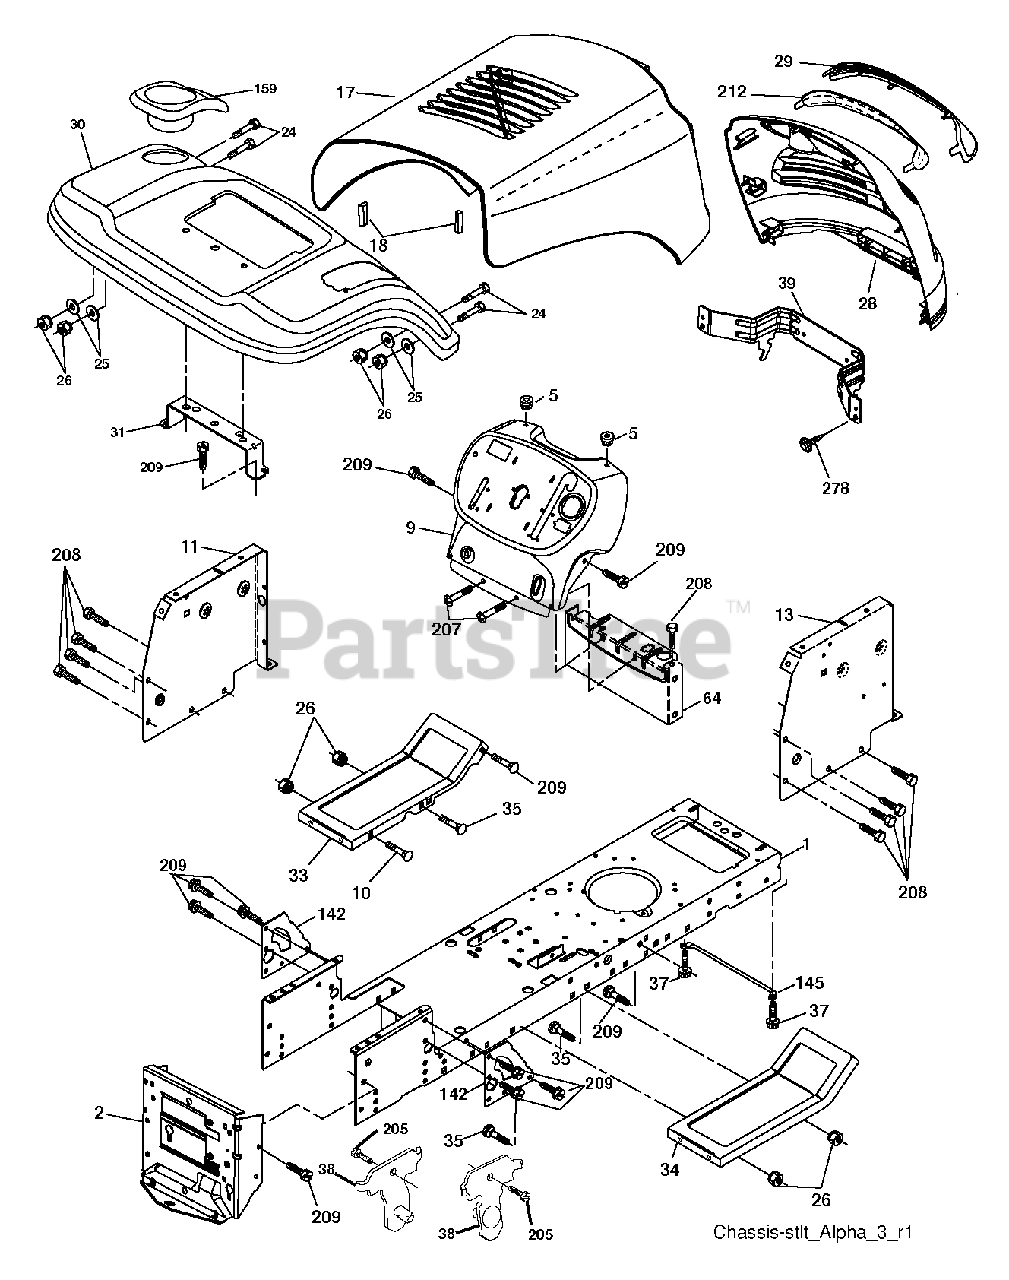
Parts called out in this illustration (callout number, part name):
1	CHASSIS STAMPING
2	DRAWBAR, 12GA
5	BUMPER.RUBBER.HOOD
11	PANEL.DASH.LH.LTX
13	PANEL
17	HOOD.BLACK.ALPHA
18	BUMPER.HOOD.LARGE.1.75"
25	WASHER
26	NUT
28	GRILLE.ASM.ALPHA
29	LENS.ALPHA.BAR.LT
30	FENDER.LTST.W/SHFT.CUP.BLACK
31	BRACKET FENDER
33	FOOTREST.LH.BLACK
34	FOOTREST.RH.BLACK
37	SCREW LT
38	BRACKET.ASM.PIVOT.MOWER.REAR
39	BRACKET.PIVOT.ALPHA.LT
64	DASH LOWER
142	PLATE REINFORCEMENT
145	ROD.PIVOT.HOOD
159	CUPHOLDER.BLACK
205	SCREW LT
207	SCREW, 5/16-18 X 1/2
208	SCREW 3/8-16X1/2
209	SCREW, 3/8-16X3/4
212	INSERT.ALPHA.REFLECTIVE.LT.
278	SCREW.#10 X 0.750.BOS (2 2)
